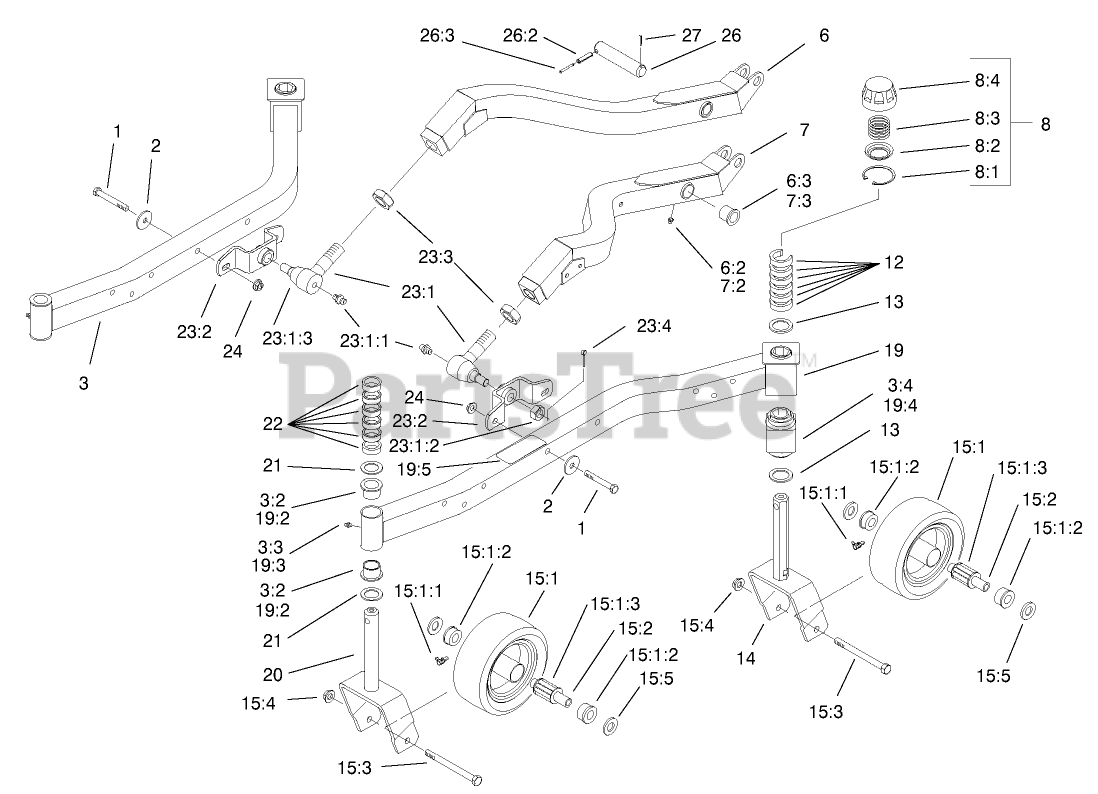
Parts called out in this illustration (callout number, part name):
1	SCREW-HH
2	WASHER
3	RH CASTOR ARM ASM
3:2	BUSHING
3:3	FITTING-GREASE
3:4	BUSHING-RUBBER, SQUARE
6	RH LIFT ARM ASM
6:2	FITTING-GREASE
6:3	BUSHING
7	LH LIFT ARM ASM
7:2	FITTING-GREASE
7:3	BUSHING
8	HOC CAP ASM
8:1	RING-RETAINING
8:2	WASHER-CAP
8:3	SPRING-COMPRESSION
8:4	CAP-HOC
12	SPACER
13	WASHER-THRUST
14	FORK-CASTOR, REAR ASM
15:1	8-INCH CASTOR WHEEL ASM
15:1:1	FITTING-GREASE, 90 DEG
15:1:2	BEARING-OUTSIDE
15:1:3	BEARING
15:2	SPANNER
15:3	SCREW-HH
15:4	NUT-HF
15:5	WASHER-FLAT
19	CASTOR ARM ASM-LH
19:2	BUSHING
19:3	FITTING-GREASE
19:4	BUSHING-RUBBER, SQUARE
19:5	DECAL-HOC
20	CASTOR FORK ASM
21	WASHER-THRUST
22	SPACER
23	Balljoint ASM
23:1	JOINT-BALL
23:1:1	FITTING-GREASE
23:1:2	NUT-SHH
23:2	BALLJOINT MOUNT ASM
23:3	NUT-HJ
23:4	PIN-COTTER
24	NUT-HF
26	PIVOT PIN ASM
26:2	PIN-SPRING
26:3	PIN-ROLL
27	PIN-COTTER
